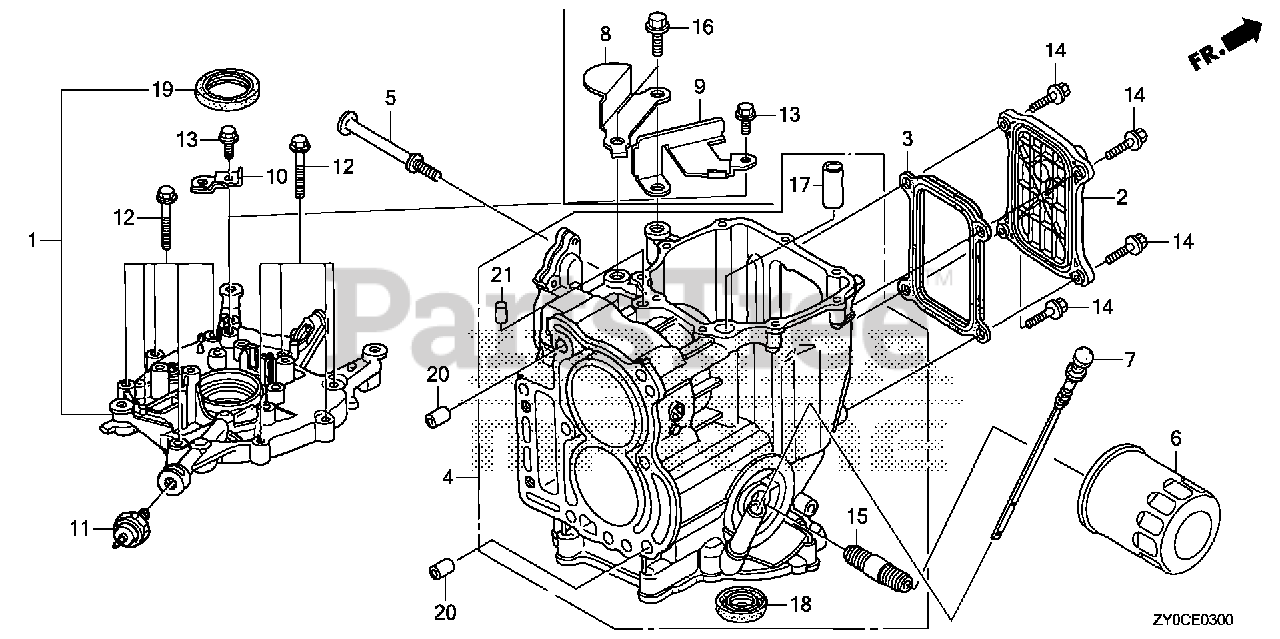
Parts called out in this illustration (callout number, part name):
1	COVER ASSY., CRANKCASE
2	COVER, CRANKCASE SIDE
3	GASKET, CRANKCASE SIDE COVER
4	BLOCK ASSY., CYLINDER *NH8* (DARK GRAY)
5	STOPPER, ENGINE SIDE
6	FILTER, OIL (TOYO ROKI)
7	DIPSTICK, OIL
8	PLATE A, FLYWHEEL COVER
9	PLATE B, FLYWHEEL COVER
11	SWITCH ASSY., OIL PRESSURE
12	BOLT, FLANGE (6X28)
13	BOLT, FLANGE (6X14) (CT200)
14	BOLT, FLANGE (6X22) (CT200)
15	HOLDER, OIL FILTER
16	BOLT, FLANGE (8X25)
17	PIN, DOWEL (14X20)
18	OIL SEAL (28X45X8)
19	OIL SEAL (35X50X8) (NOK)
20	PIN, DOWEL (10X12)
21	PIN B, DOWEL (8X14)
